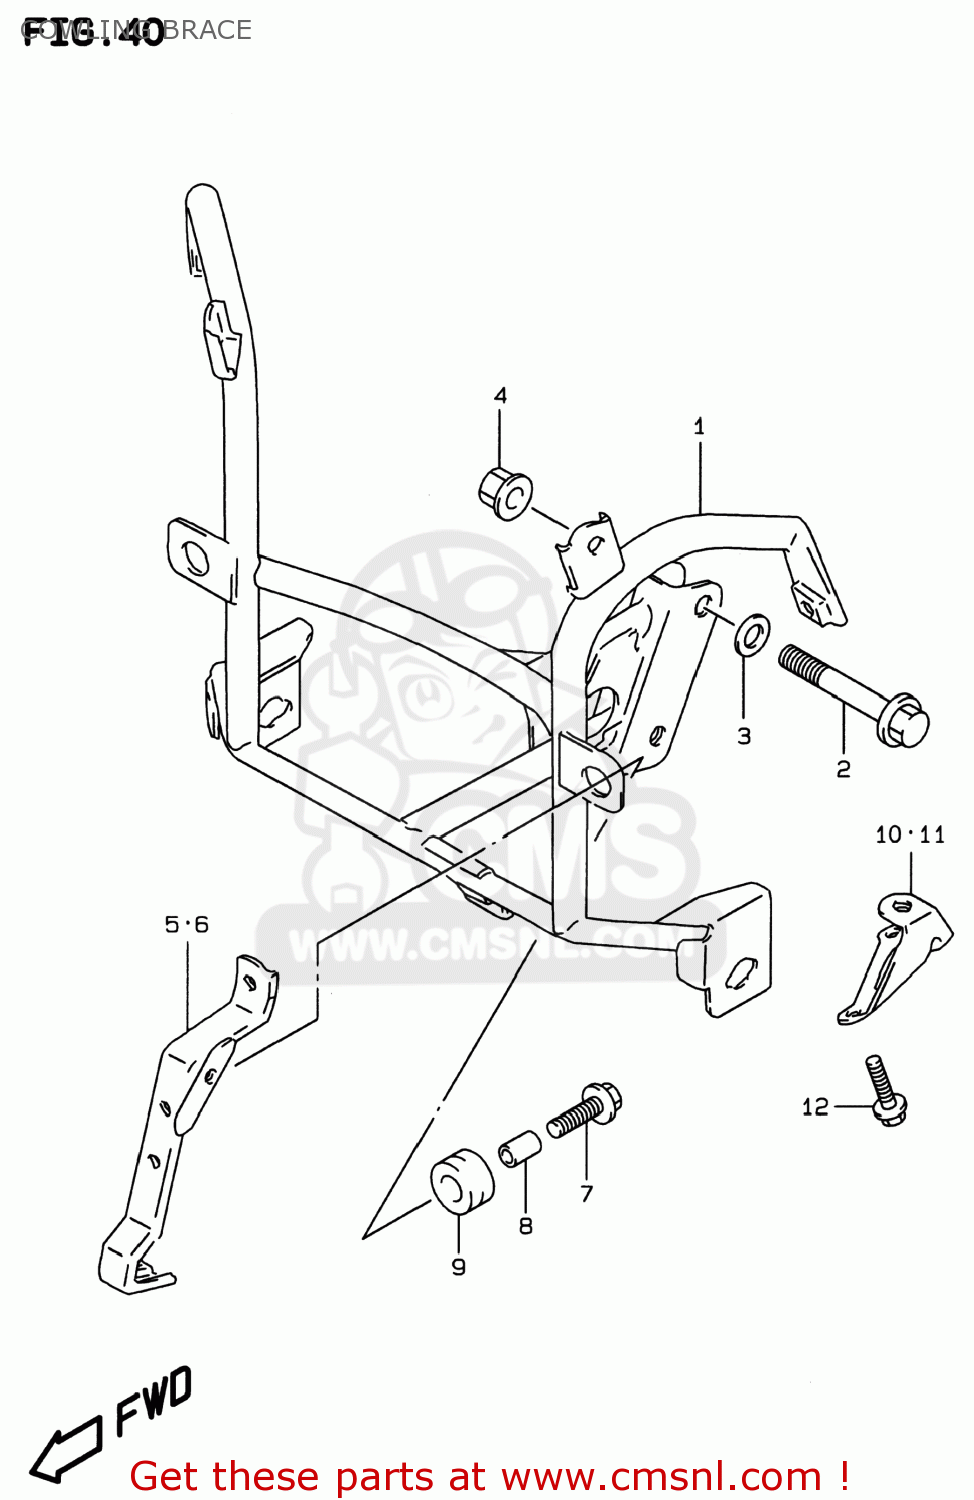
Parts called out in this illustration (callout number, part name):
1	BRACE COMP,COWLING
2	BOLT(8X40)
3	WASHER
4	NUT
5	BRACKET,HEADLAMP,R
6	BRACKET,HEADLAMP,L
7	BOLT(6X25)
8	SPACER(6.5X9X10)
9	CUSHION
10	BRACKET,COWLING RR,R
11	BRACKET,COWLING RR,L
12	BOLT
